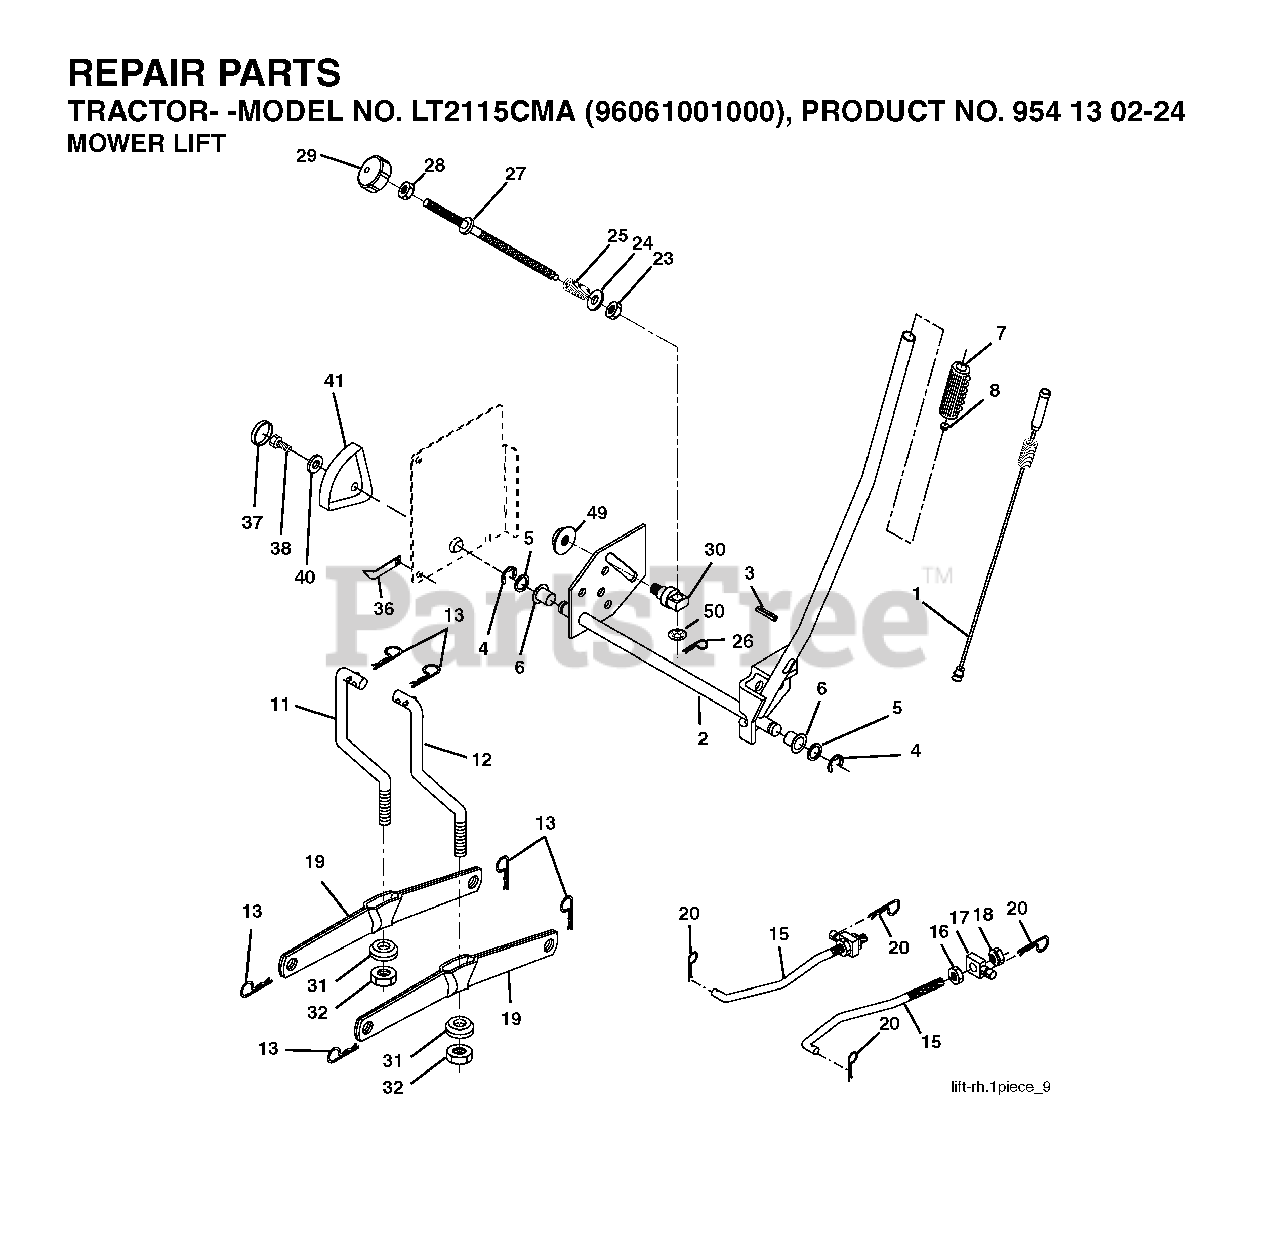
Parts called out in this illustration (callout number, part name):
1	WIRE, INNER
4	RETAINING RING LT
6	BEARING.NYLON
7	GRIP HANDLE
8	PLUNGER BUT KIT
11	LINK
12	LINK
13	RETAINER-SPRNG RB
15	LINK.SUSPENSION.FRONT
16	NUT
18	NUT
19	ARM.REAR.SUSPENSION
20	SPRING RETAINER
25	SPRING**
26	RETAINER CLIP
27	ROD ADJ LIFT
28	NUT
29	KNOB INF 3/8-16
31	BEARING.PIVOT.LIFT
32	NUT CROWNLOCK 3/8-24
36	POINTER, HEIGHT INDICATOR
37	PLUG,HOLE
38	SCREW 5/16-18X1
41	HEIGHT INDICATOR
49	NUT
50	NUT PUSH M
